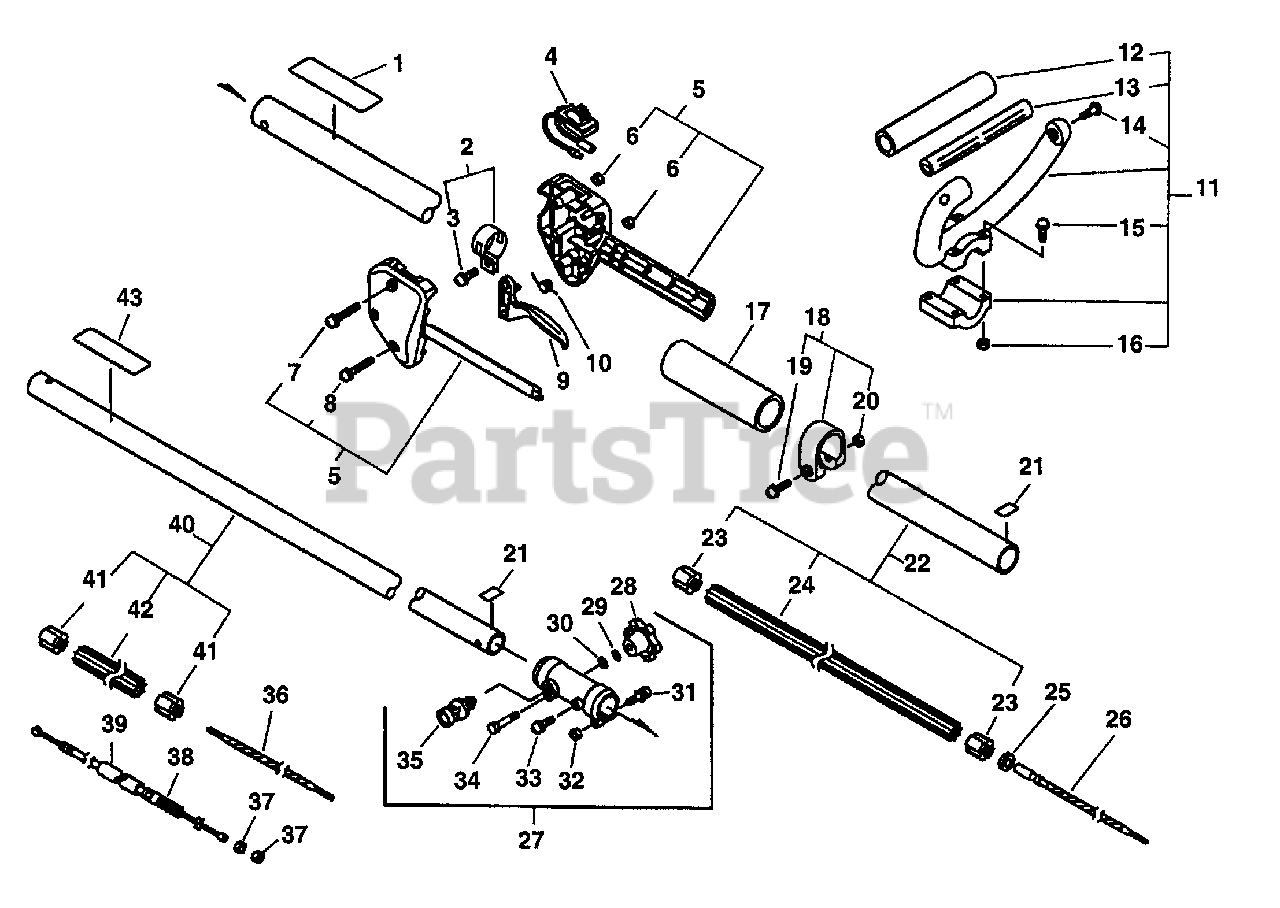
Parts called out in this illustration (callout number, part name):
1	LABEL, CAUTION
2	CLAMP KIT
3	SCREW 5×14
4	SWITCH, ON-OFF
5	HANDLE KIT, CONTROL
6	NUT M5
7	SCREW 5×35
8	SCREW 5×25
9	TRIGGER, THROTTLE
10	SPRING, TORSION
11	LOOP HANDLE ASSY
12	GRIP, HANDLE
14	SCREW 5×30
15	SCREW 5×35
16	NUT M5
17	GRIP, HANDLE
18	CLAMP KIT
19	SCREW 5×28
20	NUT M5
21	LABEL - ALIGNMENT
22	MAIN PIPE ASSY
24	LINER - FLEXIBLE
25	STOPPER
26	DRIVESHAFT - FLEXIBLE
27	COUPLER ASSY
28	KNOB, FASTENER
29	WASHER, SPRING 5
30	WASHER, FLAT 5.5×10×0.8
31	BOLT 5×30
32	NUT M5
33	SCREW 5×12
34	BOLT 5×35 SP
35	LATCH ASSY
36	DRIVESHAFT - FLEXIBLE
38	CABLE, THROTTLE
40	MAIN PIPE ASSY
42	LINER - FLEXIBLE
43	LABEL, CAUTION
